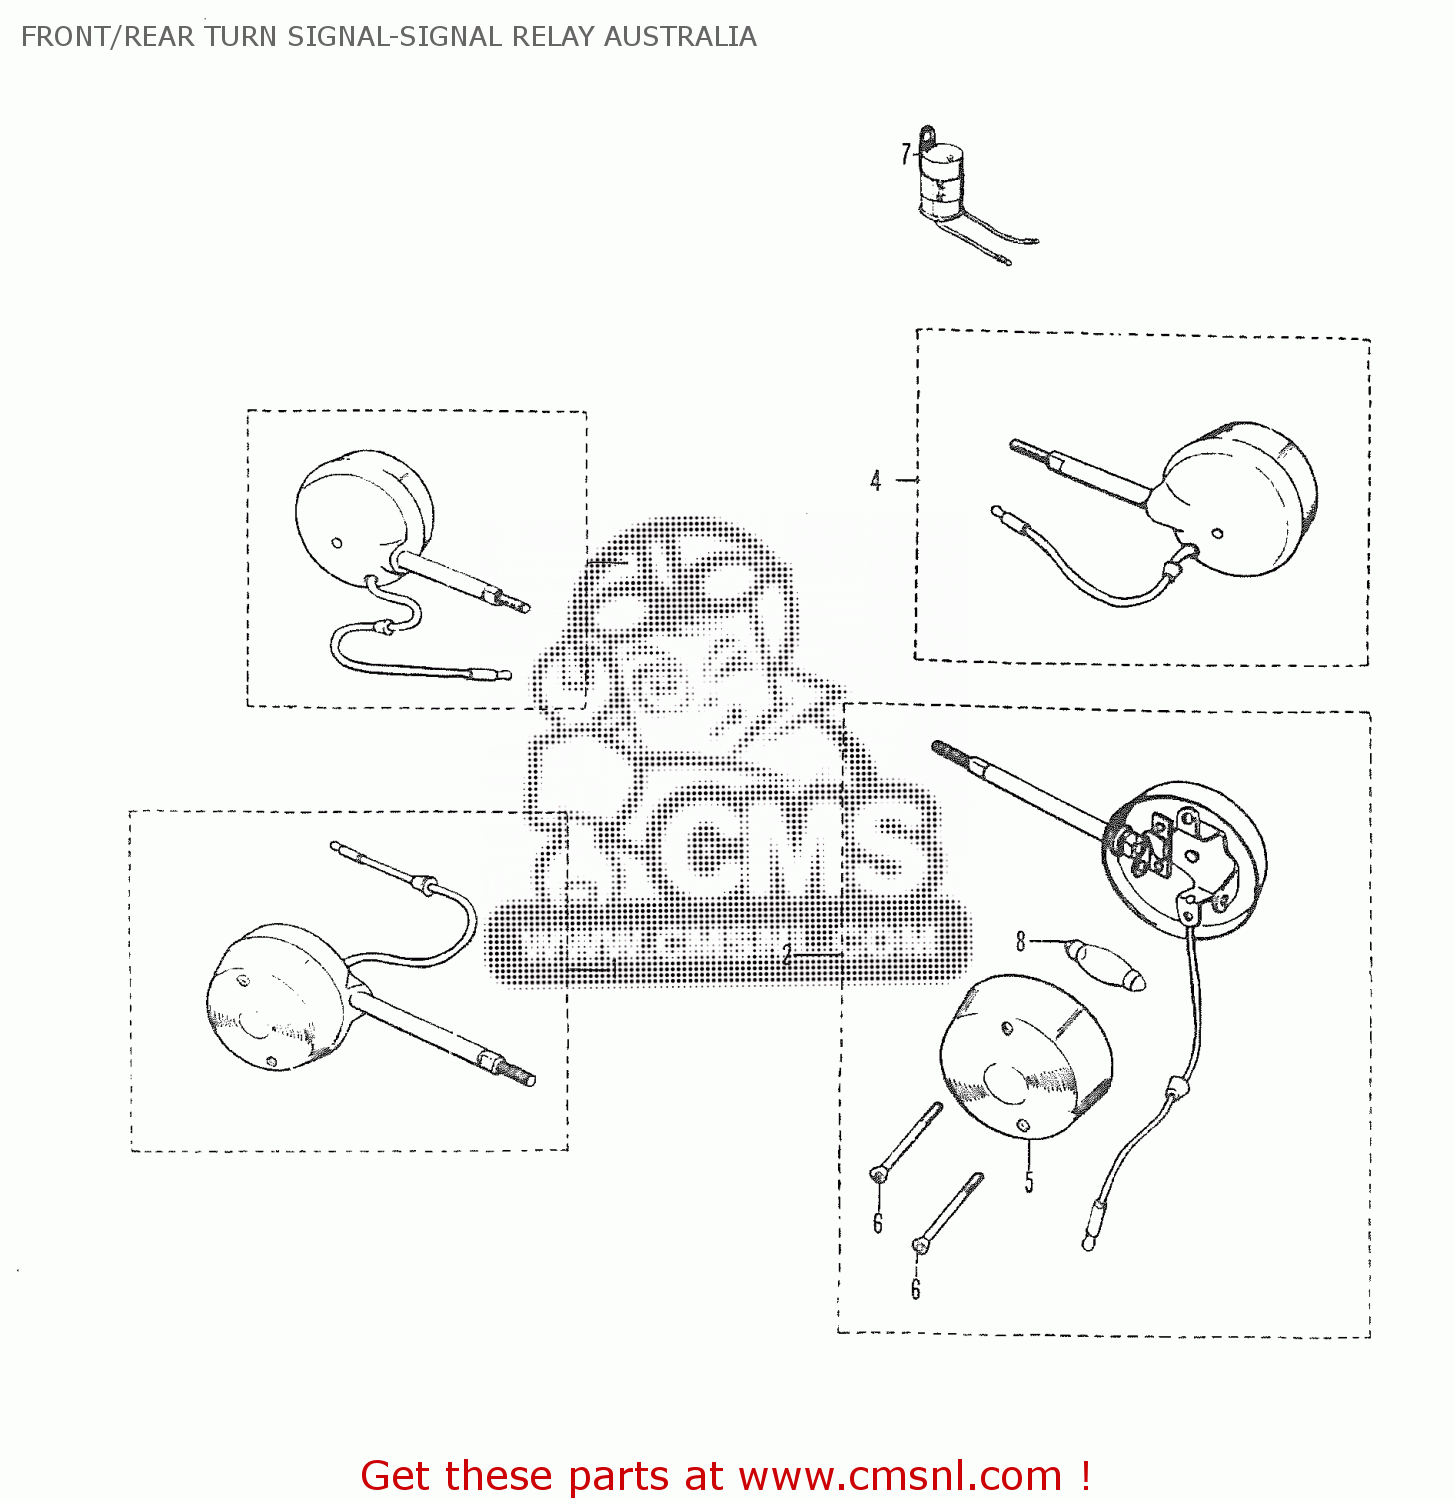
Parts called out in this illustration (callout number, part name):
1	RIGHT FRONT TURN SIGNAL ASS'Y
2	LEFT FRONT TURN SIGNAL ASS'Y
3	RIGHT REAR TURN SIGNAL ASS'Y
4	LEFT REAR TURN SIGNAL ASS'Y
5	TURN SIGNAL LENS
6	3X28 CROSS HEAD SCREW
7	TURN SIGNAL RELAY
8	BRAKE LAMP BULB
